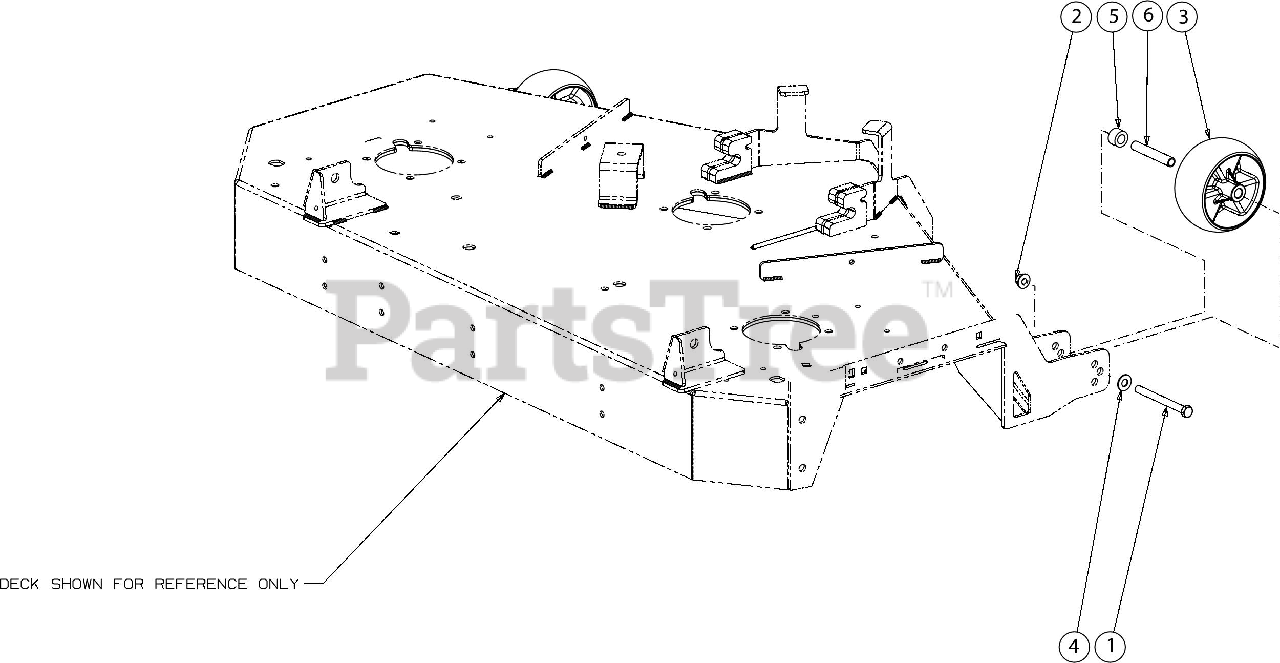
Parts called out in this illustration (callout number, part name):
1	HEX SCREW 3/8-16 X 4.00
3	DECK WHEEL
3	WHEELS-DELUXE 5"
4	FLAT WASHER
5	SPACER .502X.875X.56LG
6	SPACER .38X.49X3.05LG
